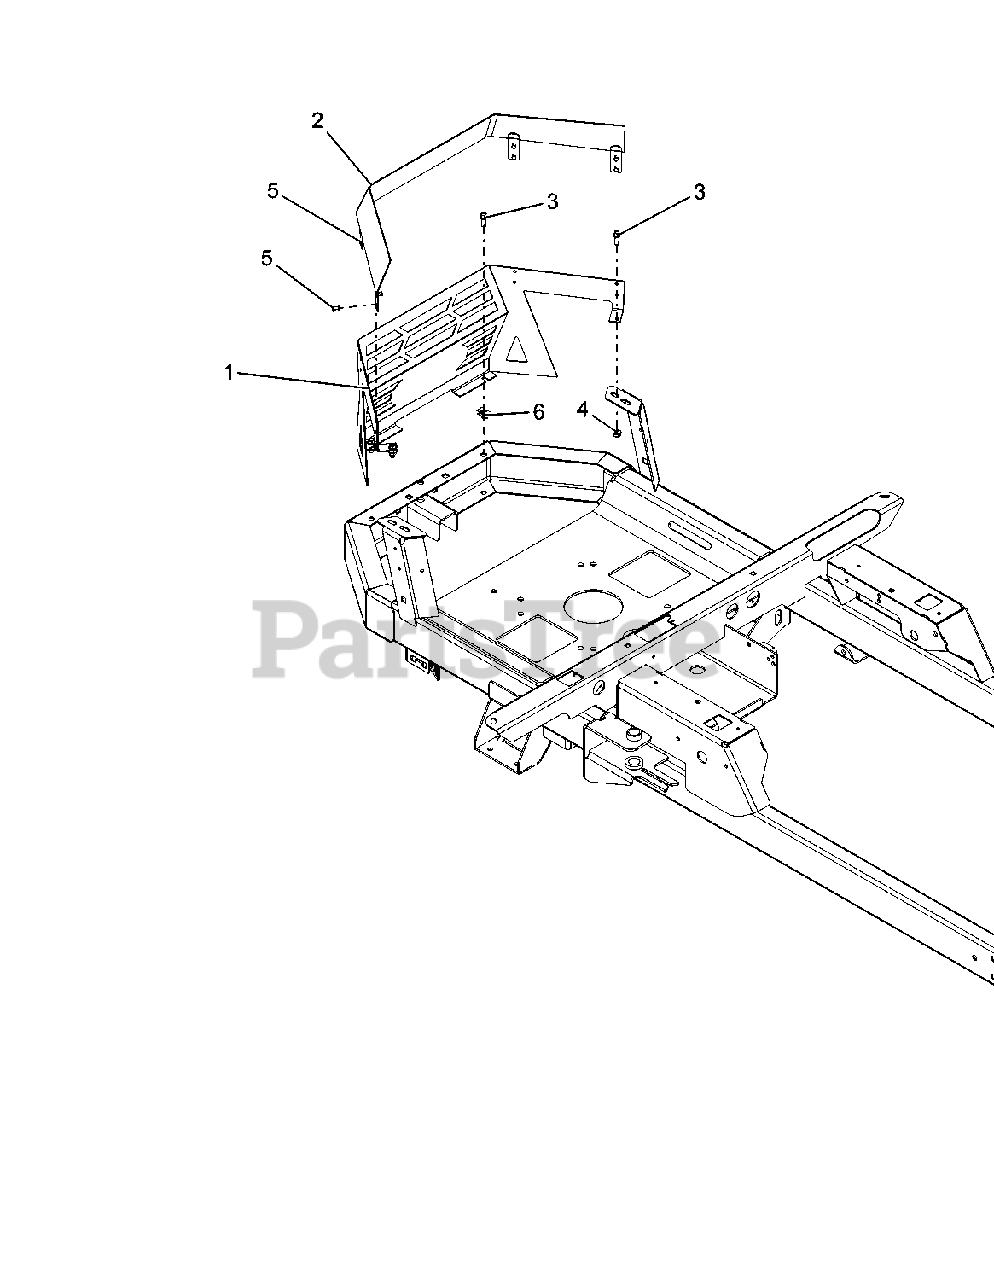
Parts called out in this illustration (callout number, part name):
1	SHROUD, ENGINE (REAR)
2	BRACKET, ENGINE SHROUD TRIM
3	BLT-HEX .25-20X.75 HWH YZ GR5
4	@NUT-LK-TOP-FLG .25-20 YWZC
5	RIVET, #66 STEEL POP PD BLACK
6	NUT-RTNR .25-20X.56
